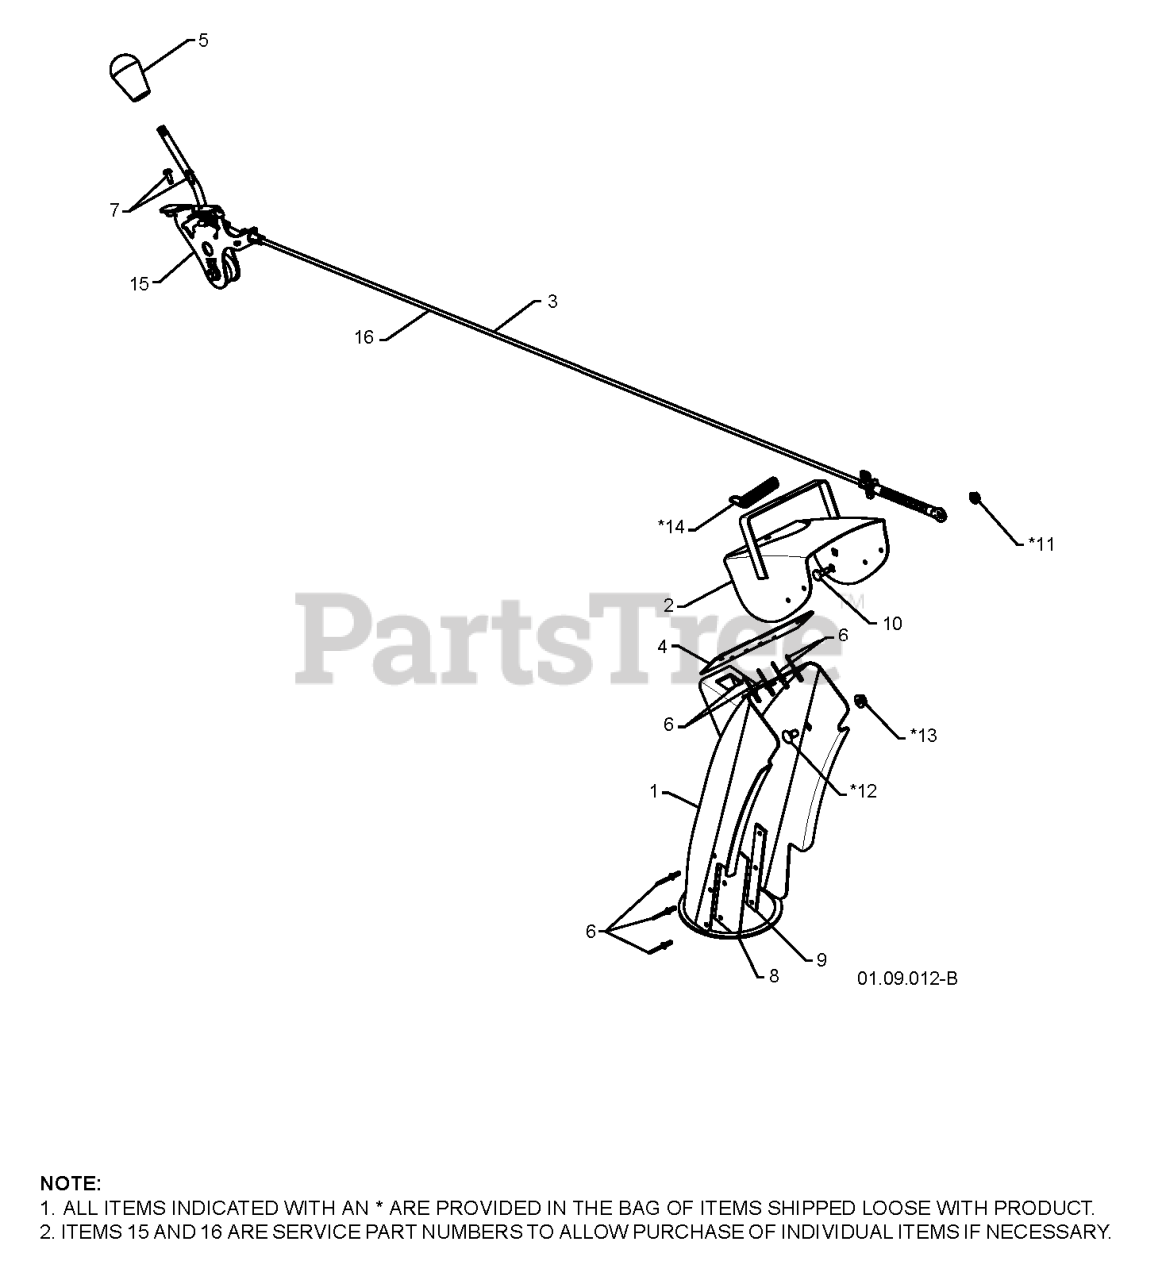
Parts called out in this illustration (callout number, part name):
1	CHUTE.WELDMENT
2	DEFLECTOR.WELDMENT.PNT.ORANGE
3	CONTROL.ASM.DEFLECTOR
4	SEAL.DEFLECTOR
5	KNOB LEVER, BLACK
6	RIVET BLIND
7	SCREW #10-24 X 5/8
8	SHIELD.SNOW.CHUTE
9	STRAP.SHEILD.RETAINER
15	RP CNTRL.HEAD.ASSEM.DEFLECTOR
16	SERVICE.CHUTE.DEF.CBL.GRY
